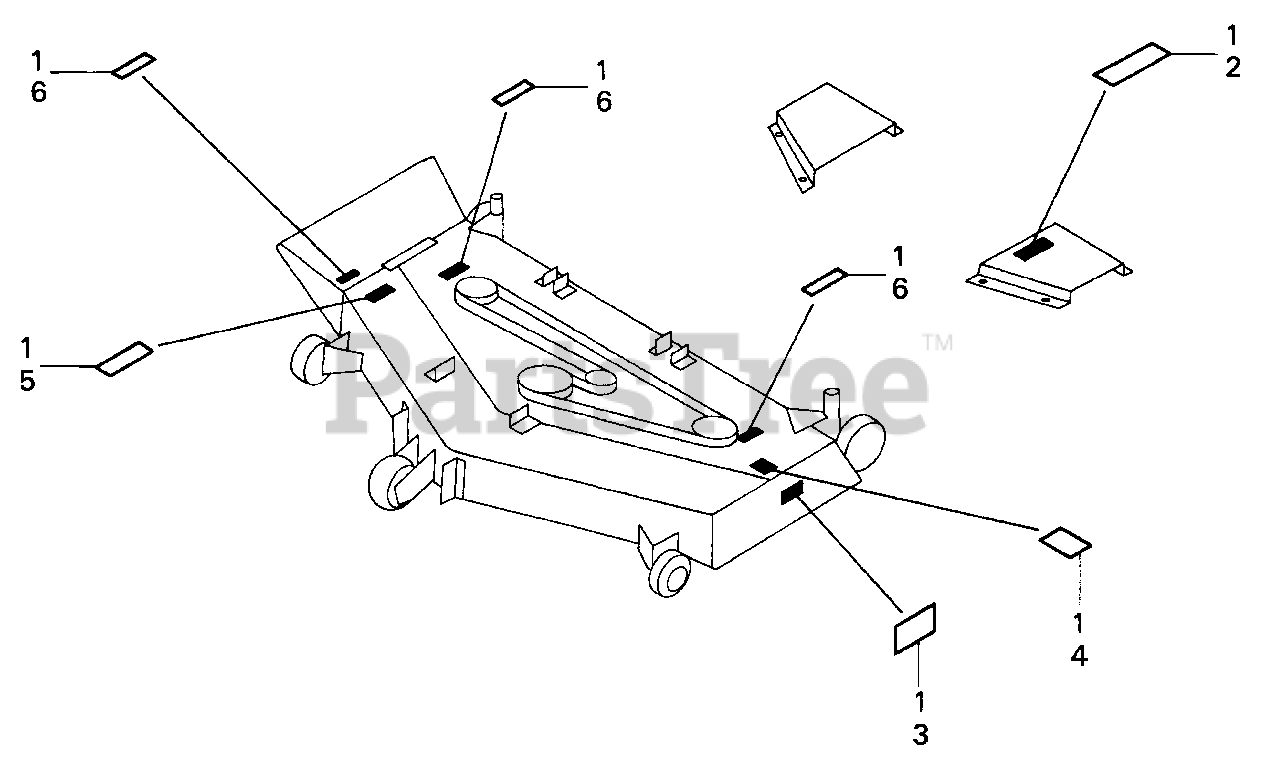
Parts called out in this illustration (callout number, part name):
2	LABEL A, WARNING (ENGLISH)
5	LABEL A, DANGER (ENGLISH)
6	LABEL B, DANGER (ENGLISH)
